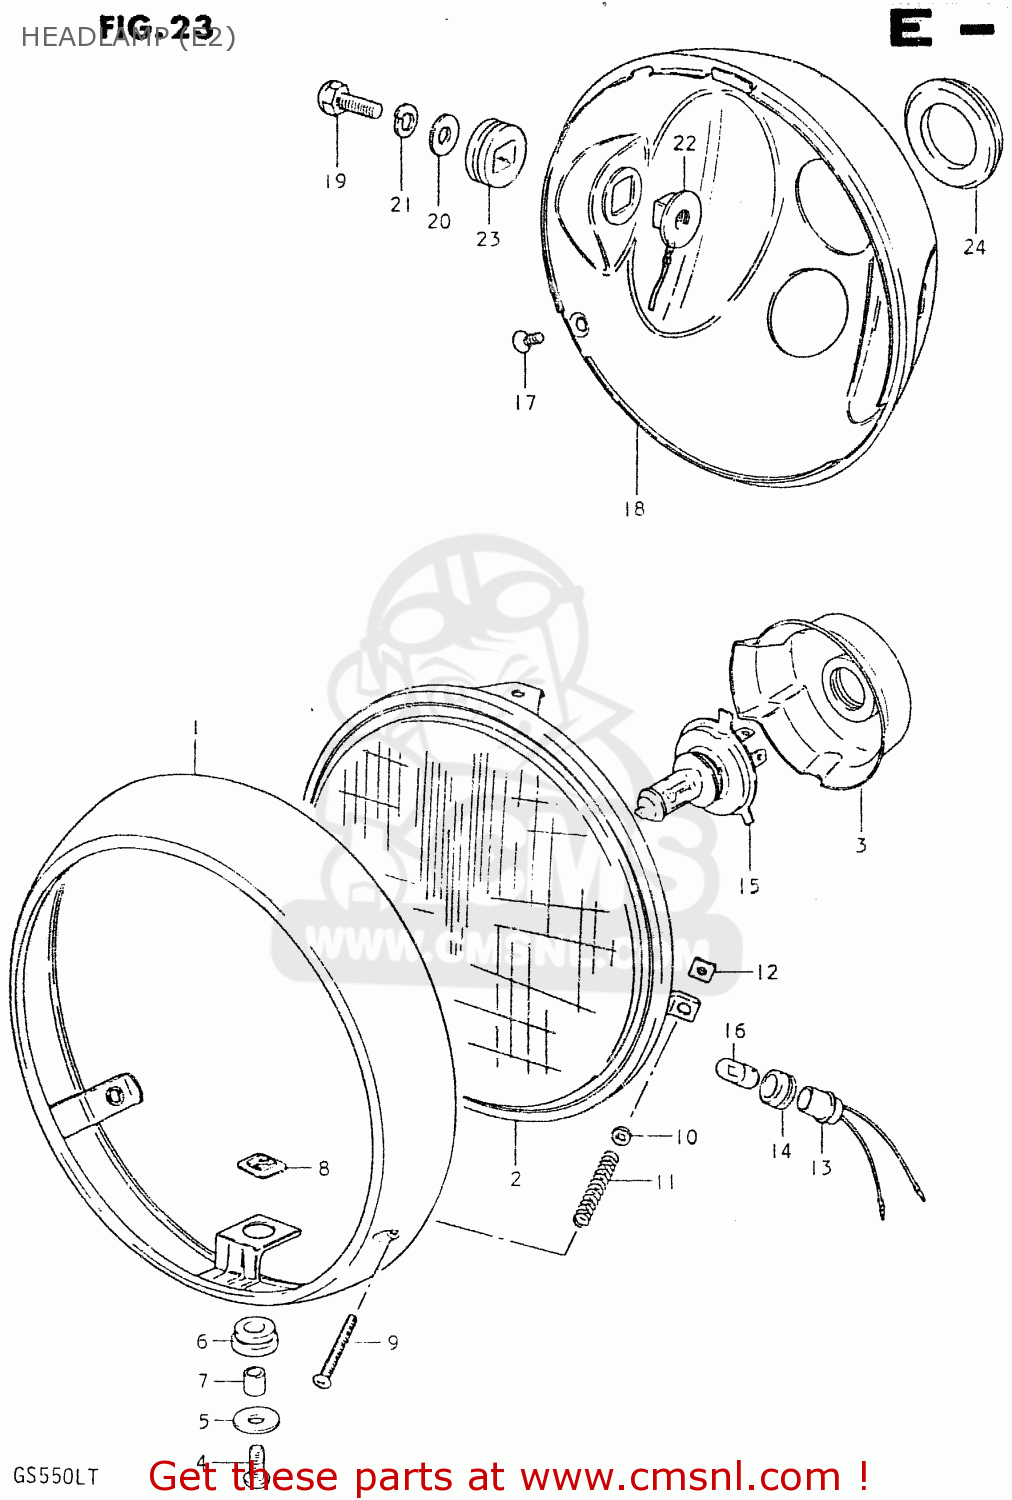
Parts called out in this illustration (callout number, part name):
1	RIM
2	UNIT
3	COVER,HEADLAMP SOCKET
4	SCREW
5	WASHER
6	CUSHION
7	SPACER
8	NUT
9	SCREW,HEADLAMP ADJUST
10	WASHER
11	SPRING,HEADLAMP ADJUST
12	NUT,HEADLAMP ADJUSTER
13	SOCKET
14	JOINT,RUBBER
15	BULB(12V60/55W,H4)
16	BULB
17	SCREW
18	HOUSING,HEADLAMP
19	BOLT
20	WASHER
21	LOCK WASHER
22	SPACER,HEADLAMP HOUSING
23	CUSHION,HEADLAMP HOUSING
24	GROMMET,HEADLAMP HOUSING
